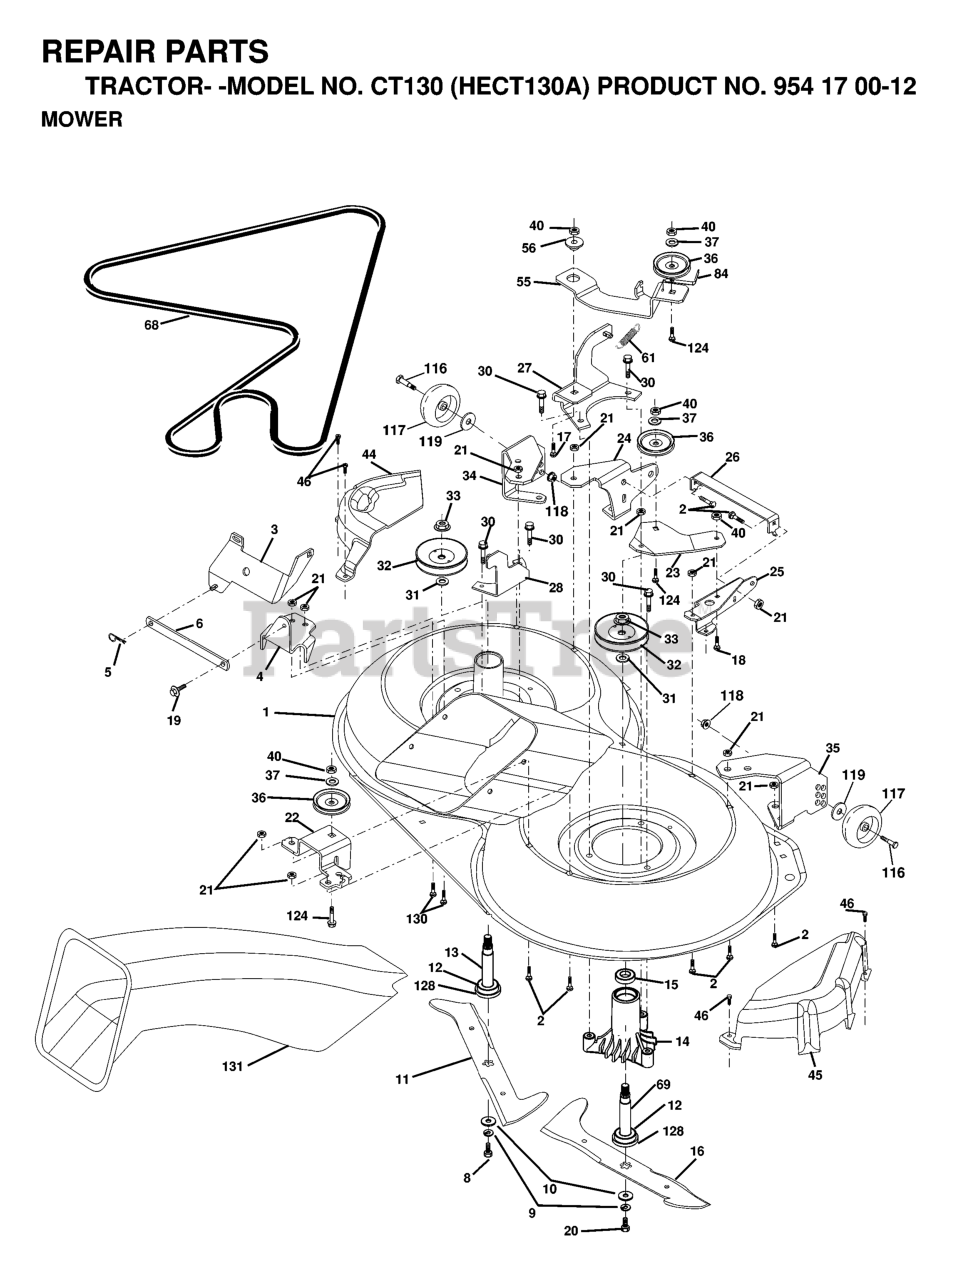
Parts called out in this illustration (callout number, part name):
1	MOWER HOUSING, DECK
2	RP BOLT 5/16-18 X3/4 ZN/YEL GR
5	RETAINER-SPRNG RB
6	BAR.SWAY.92.CRD
8	BLADE BOLT
9	LOCKWASHER
10	WASHER.BLADE
11	BLADE
12	BEARING.BALL.#6204.(MANDREL)
13	SHAFT ASM VENT
14	HOUSING.MANDREL.VENTED (MACHD)
16	BLADE.3-1.RH.CRD.92
17	BOLT.3/8-14X1.25
18	BOLT D
19	BOLT SHD 5/16-18
21	LOCKNUT
26	BRACE.SUPT.SUSP.FRT.CRD
30	SCREW THDROL ROLLING WASHER HD
31	WASHER
32	PULLEY, MANDREL
33	NUT
36	PULLEY.IDLER.4.25
37	WASHER
44	COVER.MANDREL.LH.92.CRD
45	COVER
46	SCREW.1/4-20X5/8
56	SPACER RETAINER
61	SPRING.TENSION.BELT
68	HEX-BELT 92 MOWER 105AA
69	SHAFT.ASM.W/LWR.BRG.RH.THREAD
84	KEEPER, BELT IDLER
116	BOLT, SHOULDER
117	WHEEL GAGE DONUT
118	LOCKNUT
119	WASHER.5/16.FLAT.STE.STD.
124	BOLT.3/8-16X1.50
128	WASHER FELT
130	BOLT.CARR.SQNK.5/16-18UNC.X3/4
131	CHUTE BAGGER
